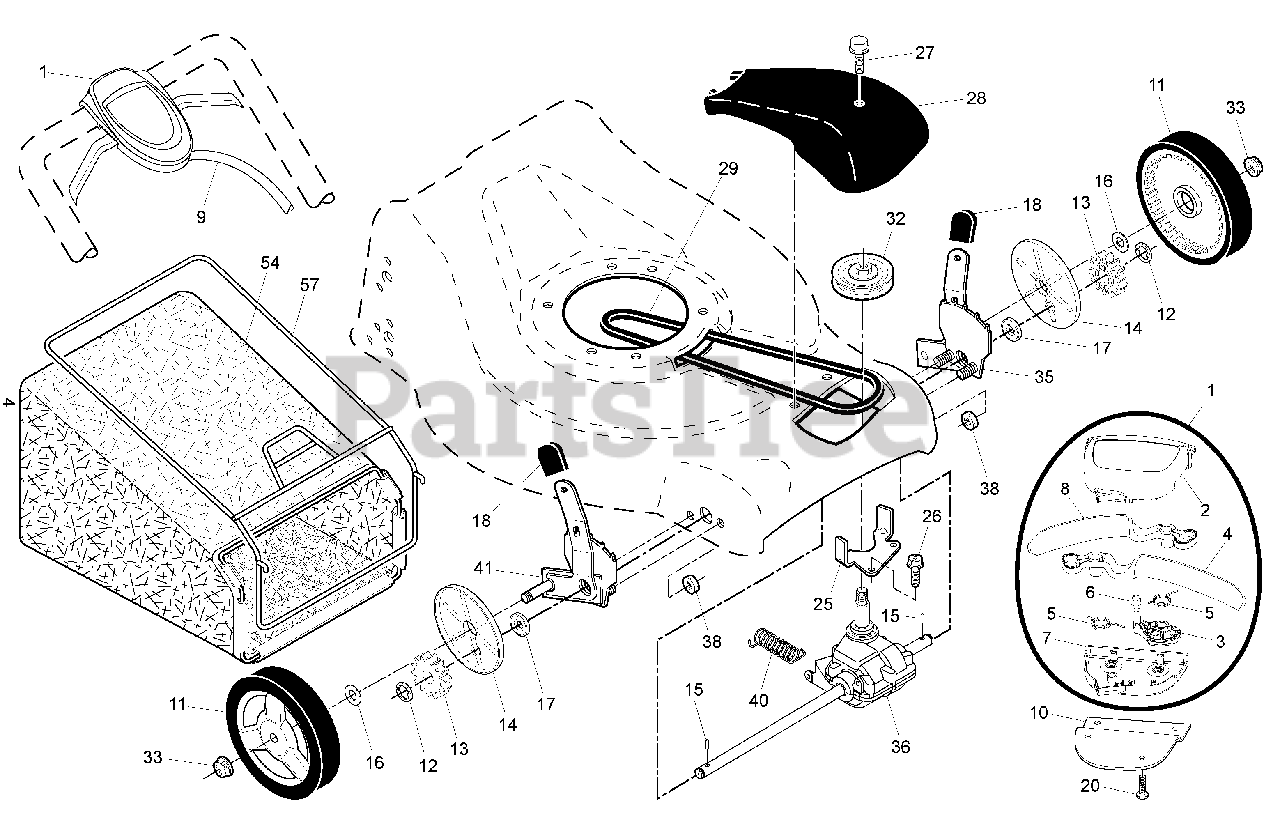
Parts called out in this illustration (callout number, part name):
1	Drive Control Assembly
2	Cover, Drive Control, Upper
4	Lever, Drive Control, LH
7	Cover, Drive Control, Lower
8	Lever, Drive Control, RH
9	Cable, Drive Control
10	Mounting Bracket, Drive Control
11	Wheel & Tire Assembly
14	Dust Cover
15	Pawl, Drive
16	Washer 1/2 x 1-1/2 x .134
17	Bearing, Wheel Adjuster
18	Selector Knob
25	Belt Keeper
26	Screw, Hi-Lo Thread #12 x 5/8
27	Screw, Pan Head, Self-Tapping #10-24 x 2-3/4
28	Drive Cover
32	Pulley, Drive
33	Locknut, Hex
35	Kit, Wheel Adjuster, LH
36	Gear Case Assembly, Complete
38	Locknut 1/4-20
41	Kit, Wheel Adjuster, RH
54	Grassbag
57	Frame, Grassbag
